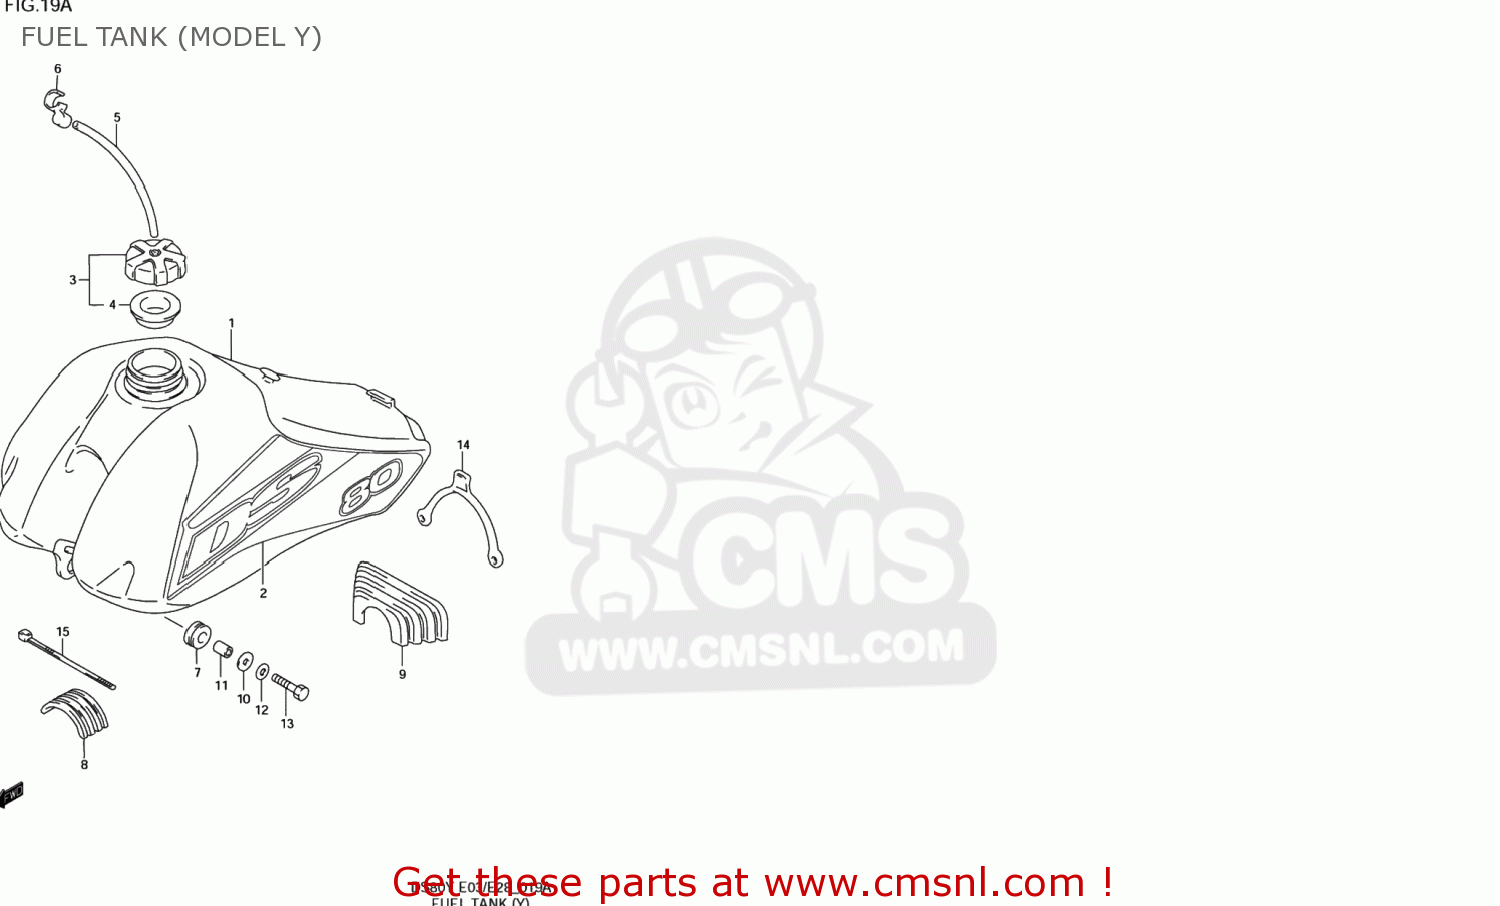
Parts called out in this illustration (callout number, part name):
1	TANK ASSY,FUEL(YELLOW)
2	EMBLEM SET,FUEL
3	CAP SET,FUEL TANK
4	GASKET (NAS)
5	HOSE(5X8.2X600)
6	CLAMP
7	CUSHION
8	CUSHION,FUEL TANK UPR FR
9	CUSHION,FUEL TANK UPR RR
10	WASHER(6.5X24X1.6)
11	SPACER(6.5X10X13.5)
12	LOCK WASHER
13	BOLT
14	BAND,FUEL TANK RR
15	CLAMP(L:250)
